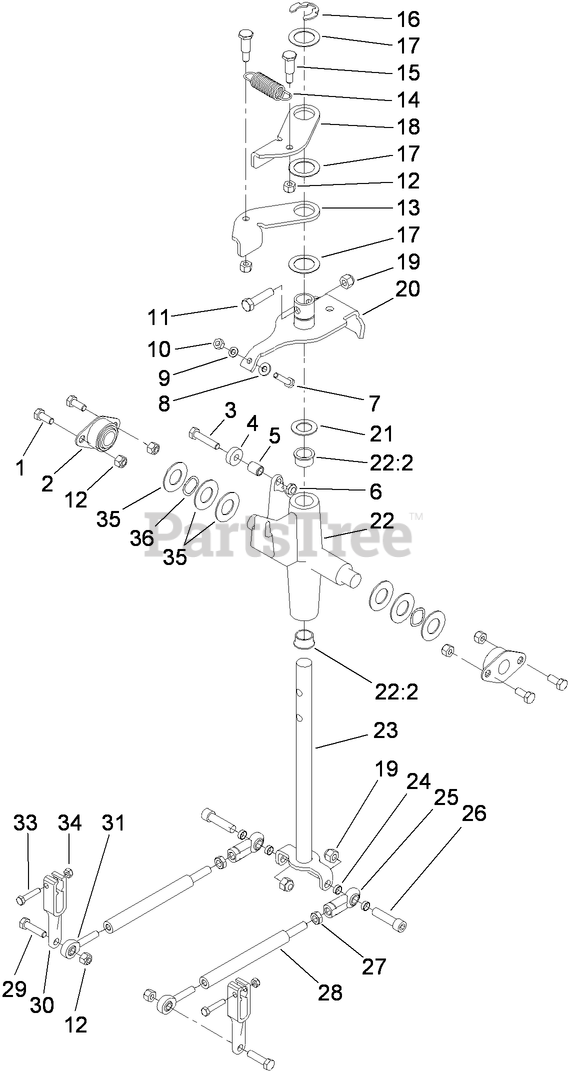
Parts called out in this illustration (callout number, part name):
1	SCREW-HH
2	BUSHING
3	SCREW-HH
4	BEARING-BALL
5	SPACER-LEVER, CONTROL
6	NUT-LOCK, NI
7	SCREW-HH
8	WASHER-FLAT
9	WASHER-LOCK
10	NUT-HEX
11	SCREW-HH
12	NUT-LOCK, NI
13	LEVER-RETURN, RH
14	SPRING-EXTENSION
15	SCREW-SHOULDER
16	RING-RETAINING
17	WASHER-PLAIN
18	LEVER-RETURN, LH
19	NUT-LOCK, NI
20	LEVER-PIVOT
21	WASHER-THRUST
22	CONTROL SUPPORT ASM
22:2	BEARING-FLANGE
23	ROD-DRIVE
24	SPACER
25	JOINT-BALL END, LH
26	SCREW-HSH
27	NUT-HEX JAM, LH
28	ROD-LINKAGE
29	SCREW-HH
30	ARM-CONTROL, PUMP
31	BEARING-ROD END, RH
33	SCREW-HH
34	NUT-LOCK, NI
35	WASHER-FLAT
36	WASHER-SPRING, WAVE
